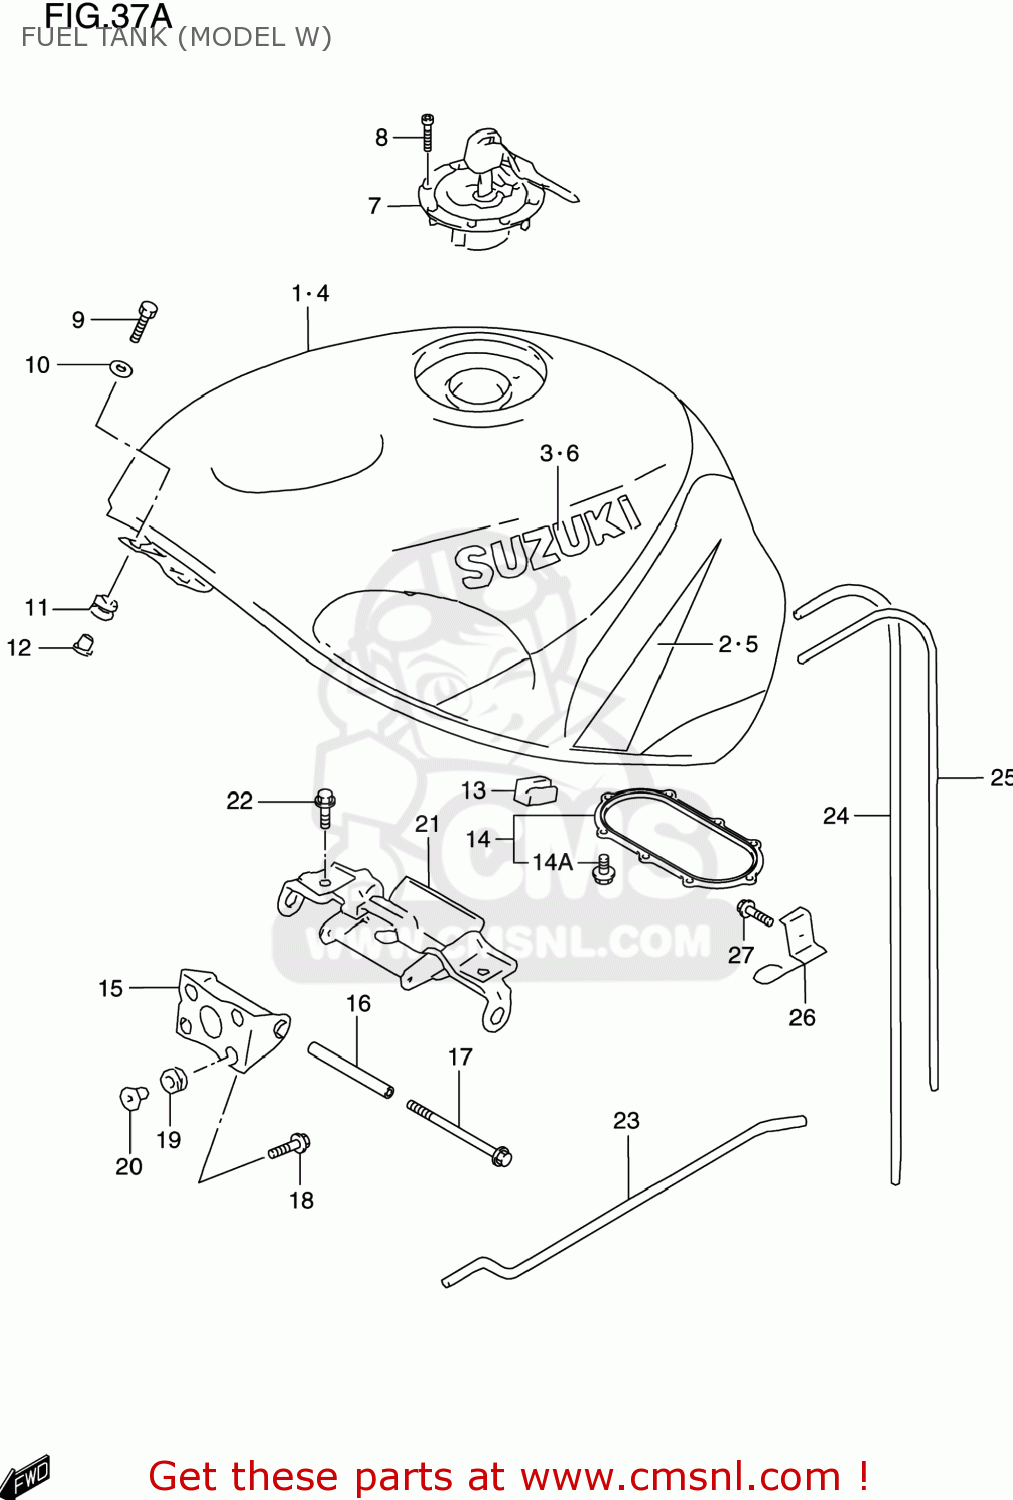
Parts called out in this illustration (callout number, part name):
1	TANK ASSEMBLY,FUEL
2	TAPE SET,FUEL TANK
3	EMBLEM,FUEL TANK
4	TANK ASSEMBLY,FUEL
5	TAPE SET,FUEL TANK
6	EMBLEM,FUEL TANK
7	CAP SET,FUEL TANK
8	BOLT(5X20)
9	SCREW(6X25)
10	WASHER(6.5X18X1.6)
11	CUSHION
12	WASHER
13	CUSHION,FUEL TANK SIDE
14	PACKING SET,FUEL PUMP (NAS)
14A	BOLT,FUEL PUMP
15	BRACKET COMP,FUEL TANK
16	SPACER,FUEL TANK RR
17	BOLT
18	BOLT 6X20,WITH PLAIN WASHER
19	CUSHION
20	WASHER
21	BRACKET,FUEL TANK NO.2
22	BOLT
23	STAY,FUEL TANK
24	HOSE(5X8.2X600)
25	HOSE(7X10.2X600)
26	GUIDE COMP,DRAIN HOSE
27	BOLT
